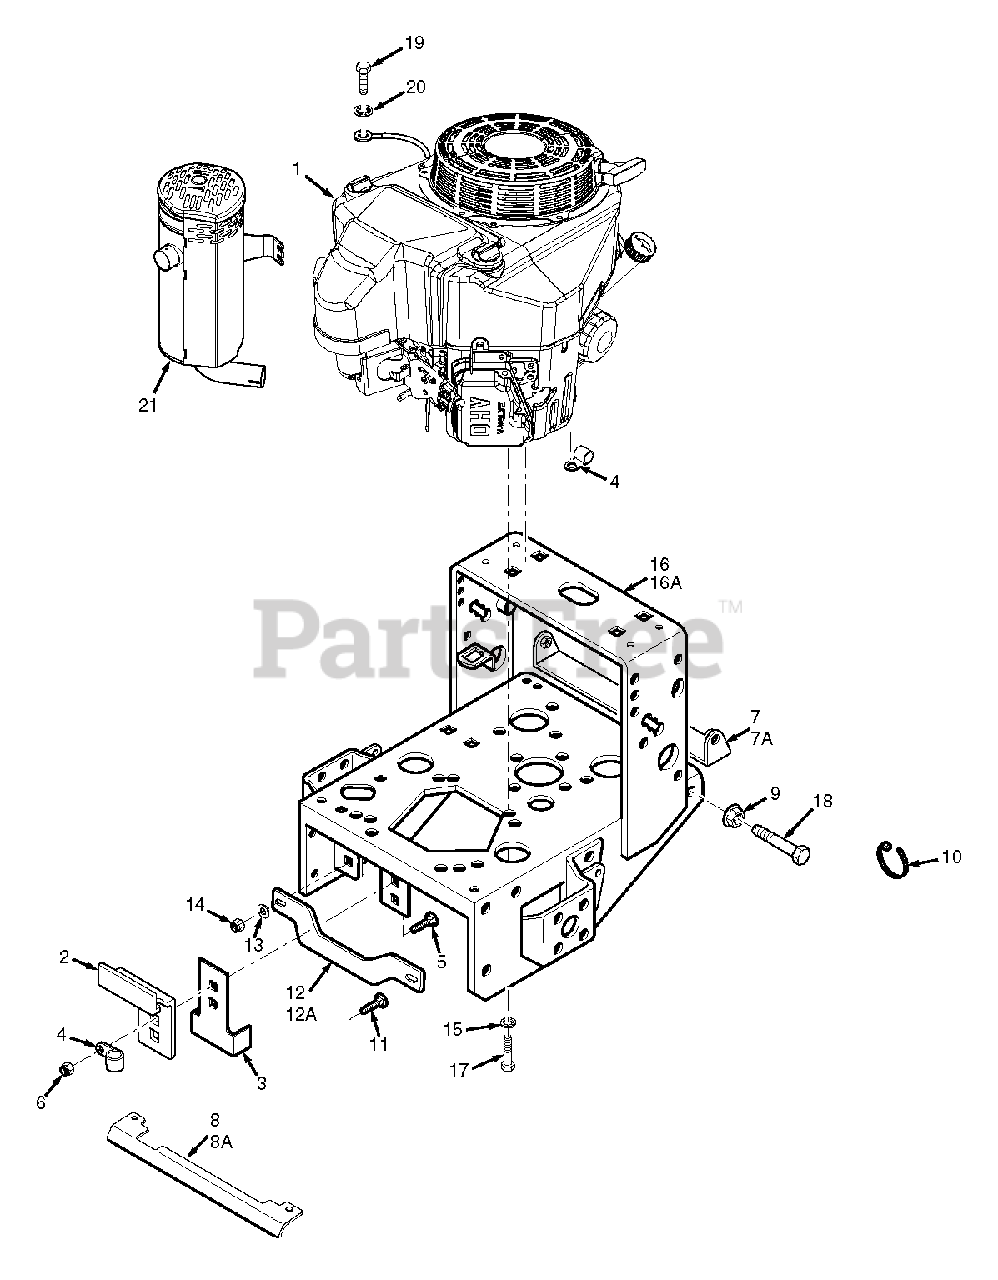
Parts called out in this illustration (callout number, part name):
1	Engine, Kawasaki 14FS (FS481V)
1	Engine, Kawasaki 15FS (FS541V)
1	Engine, Kawasaki 18FS (FS600V)
2	Plate, Clutch Bracket
3	Clutch Bracket
5	Bolt, Carriage 5/16-18 x 1'
6	Nut, 5/16-18 Elastic Stop
7	Pulley Guard, 16' Small Frame
7A	Pulley Guard, 20' Large Frame
8	Heatshield, 16' Small Frame
8A	Heatshield, 20' Large Frame
9	Nut, 5/16-18 Serr. Flange
10	Cable Tie
11	Bolt, Carriage 3/8-16 x 1-1/4'
12	Brace, 16' Small Frame
12A	Brace, 20' Large Frame
13	Flatwasher, .391 x .938 x .105
14	Nut, 3/8-16 Elastic Stop
15	Lockwasher, 3/8'
16	Engine Deck, 16' Wide w/Decals
16A	Engine Deck, 20' Wide w/Decals
17	Bolt, Hex Head 3/8-16 x 1-1/4'
18	Bolt, 5/16-18 x 2' Hex Head
19	Bolt, Hex Head M8-1.25 x 16
20	Lockwasher, 5/16' Ext. Tooth
21	Muffler, Kawasaki FS/FX
